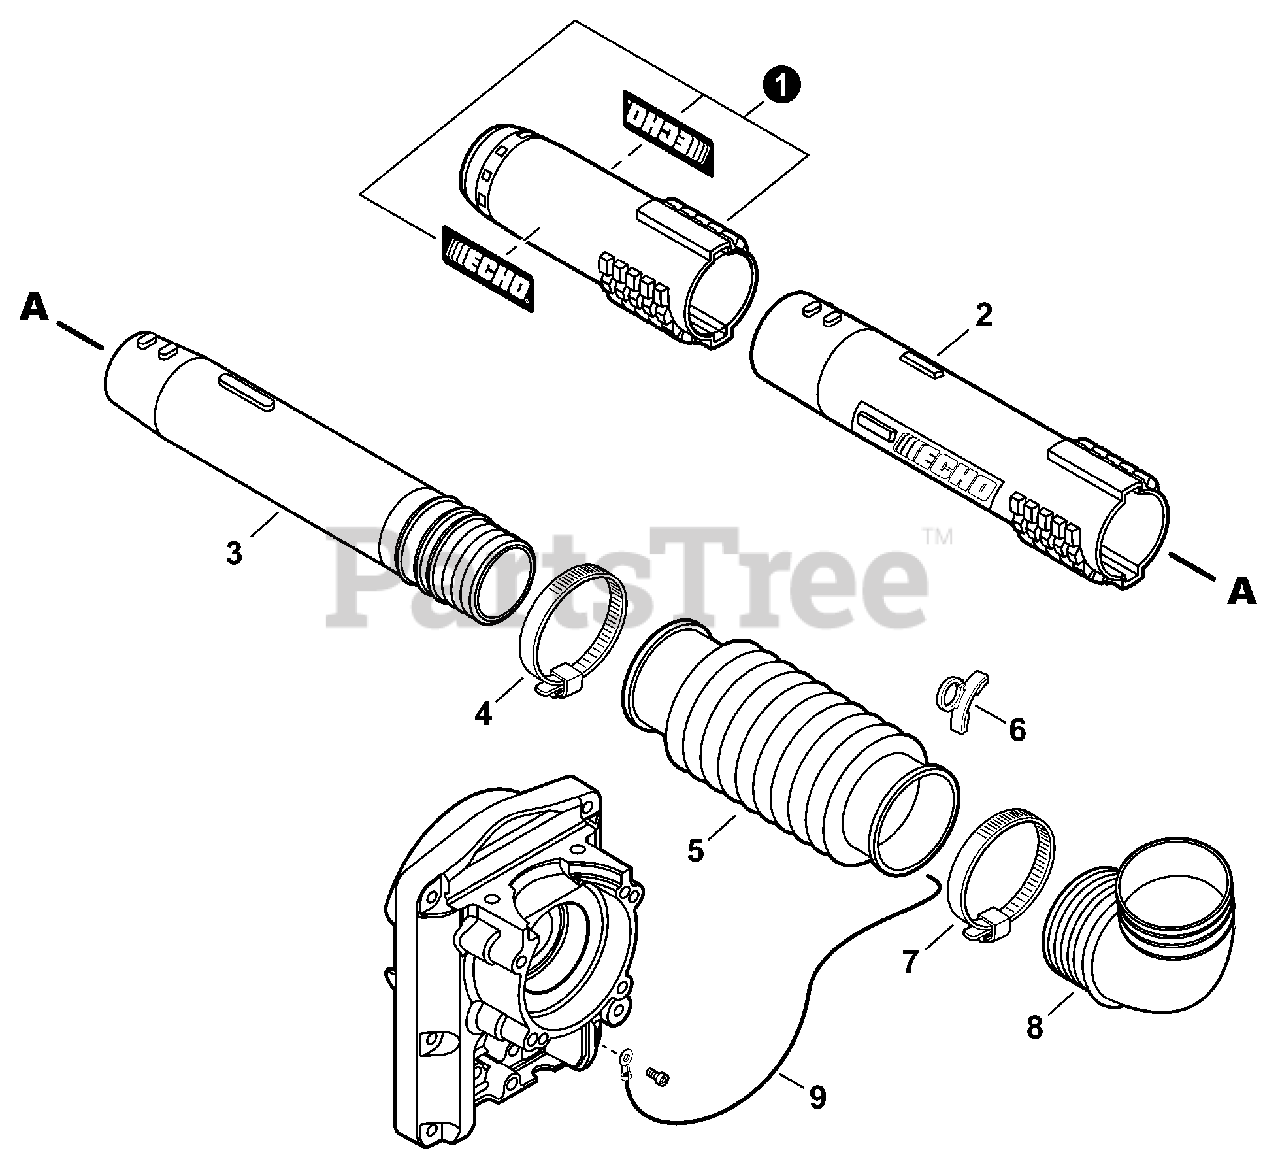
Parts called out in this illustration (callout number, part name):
1	TUBE SET, BLOWER - NOZZLE
2	TUBE, BLOWER - STRAIGHT
3	TUBE, BLOWER - SWIVEL
4	CLAMP 58.7MM / 82.5MM
5	TUBE, BLOWER - FLEXIBLE
6	CLIP, CABLE
7	CLAMP 77.8MM /101.6MM
8	TUBE, BLOWER - ELBOW
9	WIRE, STATIC DISCHARGE
